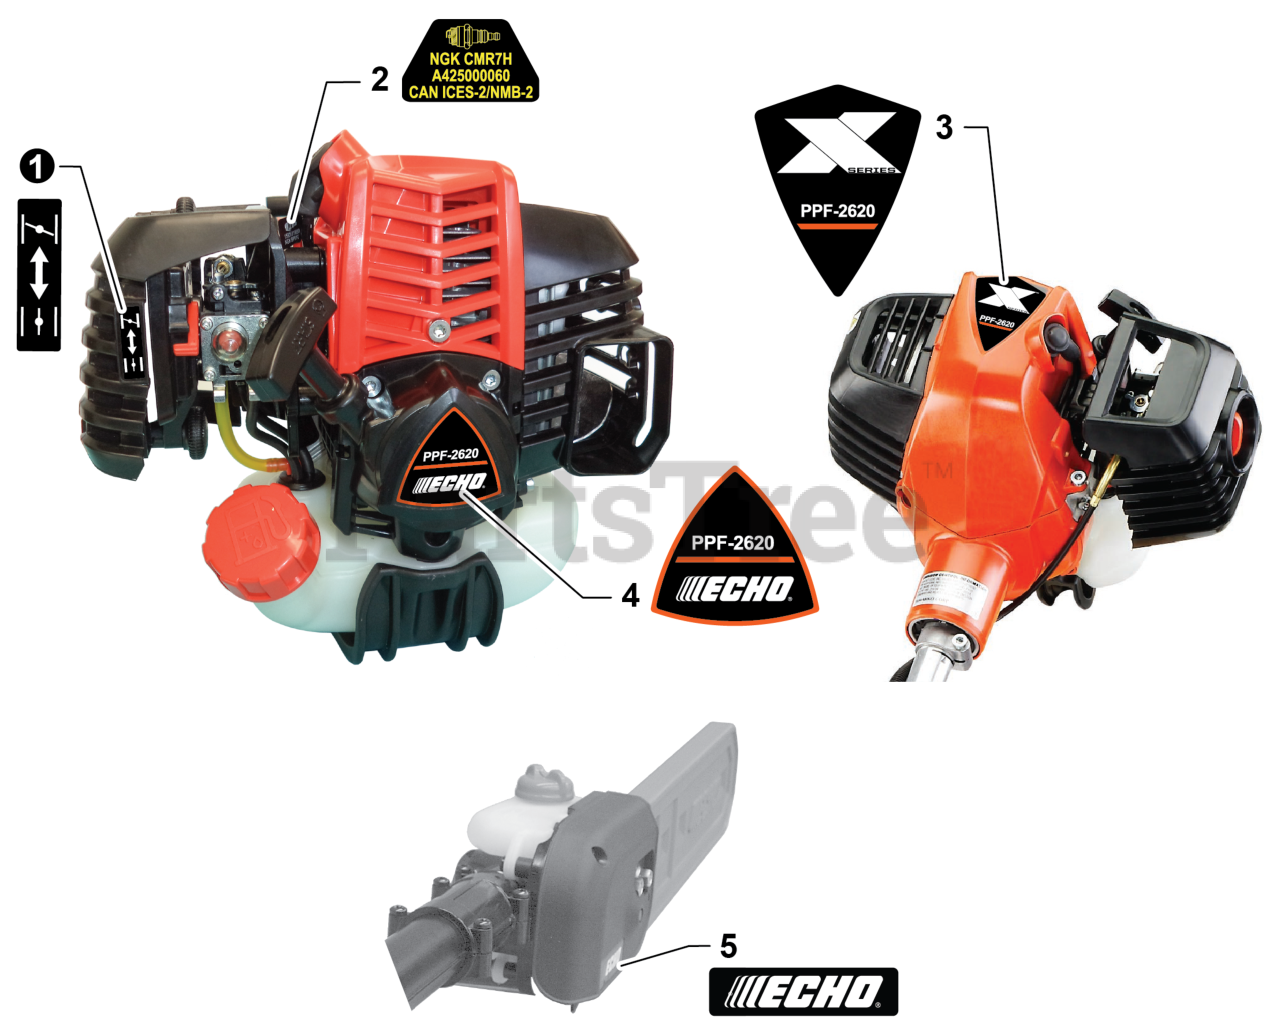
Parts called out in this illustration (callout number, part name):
1	LABEL - CHOKE
2	LABEL - SPARK PLUG - CMR7H
3	LABEL - MODEL PPF-2620
4	LABEL - RECOIL STARTER - PPF-2620
5	LABEL - ECHO
